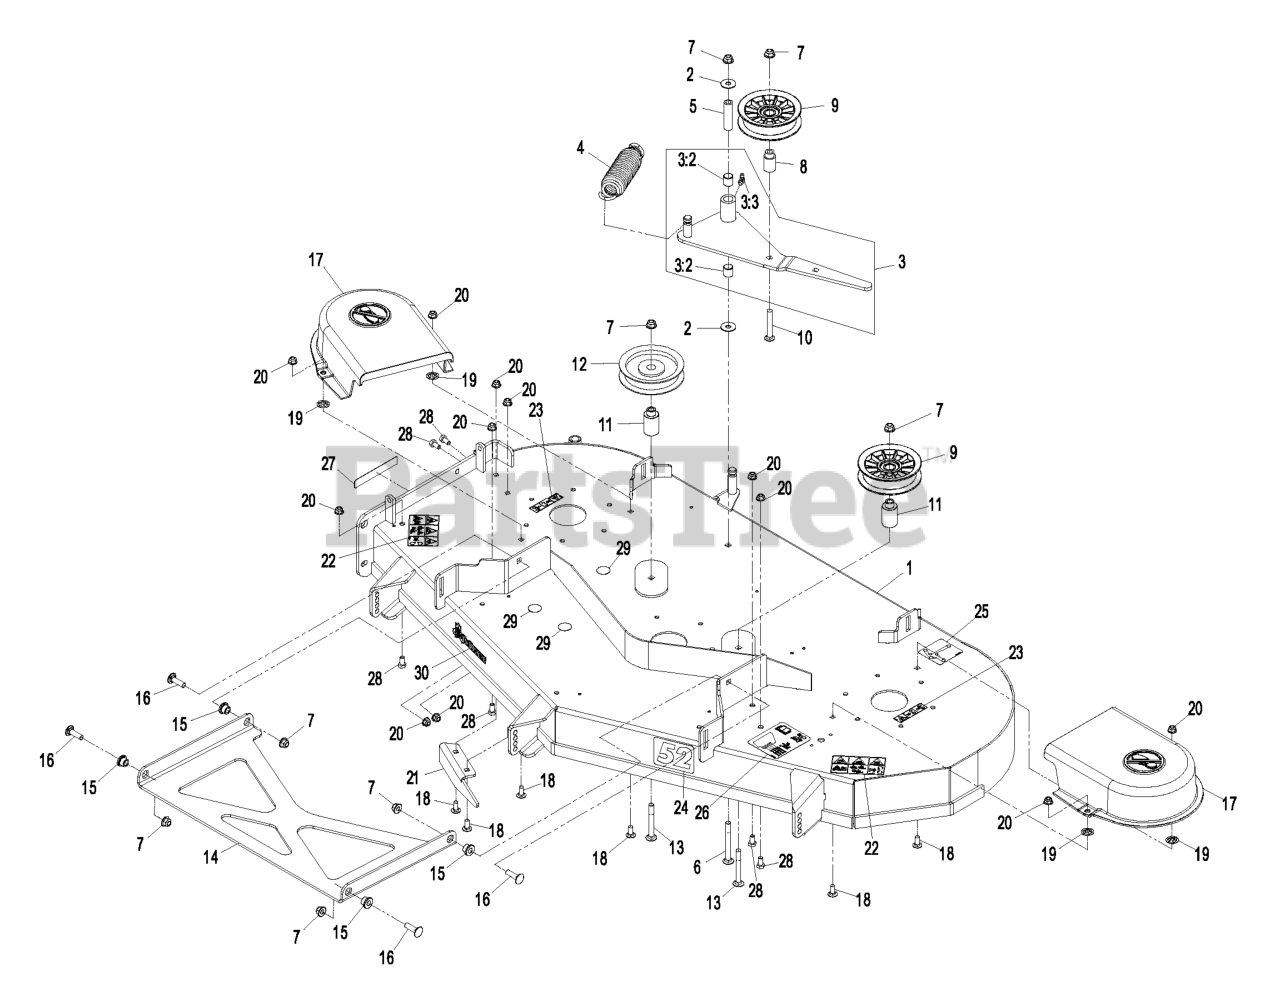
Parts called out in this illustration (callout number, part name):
1	52 INCH DECK ASM
3	IDLER ARM ASM
3:2	SLEEVE-BEARING
3:3	FITTING-GREASE, 90 DEG
4	SPRING, EXTENSION
5	BUSHING-PIVOT, IDLER
6	SCREW-CARR
7	NUT-HF, NI
8	BUSHING-IDLER
10	SCREW-CARR
11	BUSHING-IDLER
13	BOLT-CARRIAGE
14	STRUT-DECK
15	SPACER-STRUT
16	Bolt-Carriage 3/8-16 X 1 1/4
17	SHIELD-BELT
18	SCREW-CARR
19	RING-RETAINING
20	NUT-HF, NI
21	BAFFLE-DISCHARGE
22	DECAL-DANGER
23	DECAL-WARNING, BELT SHIEL
24	DECAL,DECK 52
25	DECAL-ROUTING, BELT
26	DECAL-ROLLER, ANTI-SCALP
27	DECAL-DANGER
28	SCREW-HH
31	Asm, 52 Deck Complete
